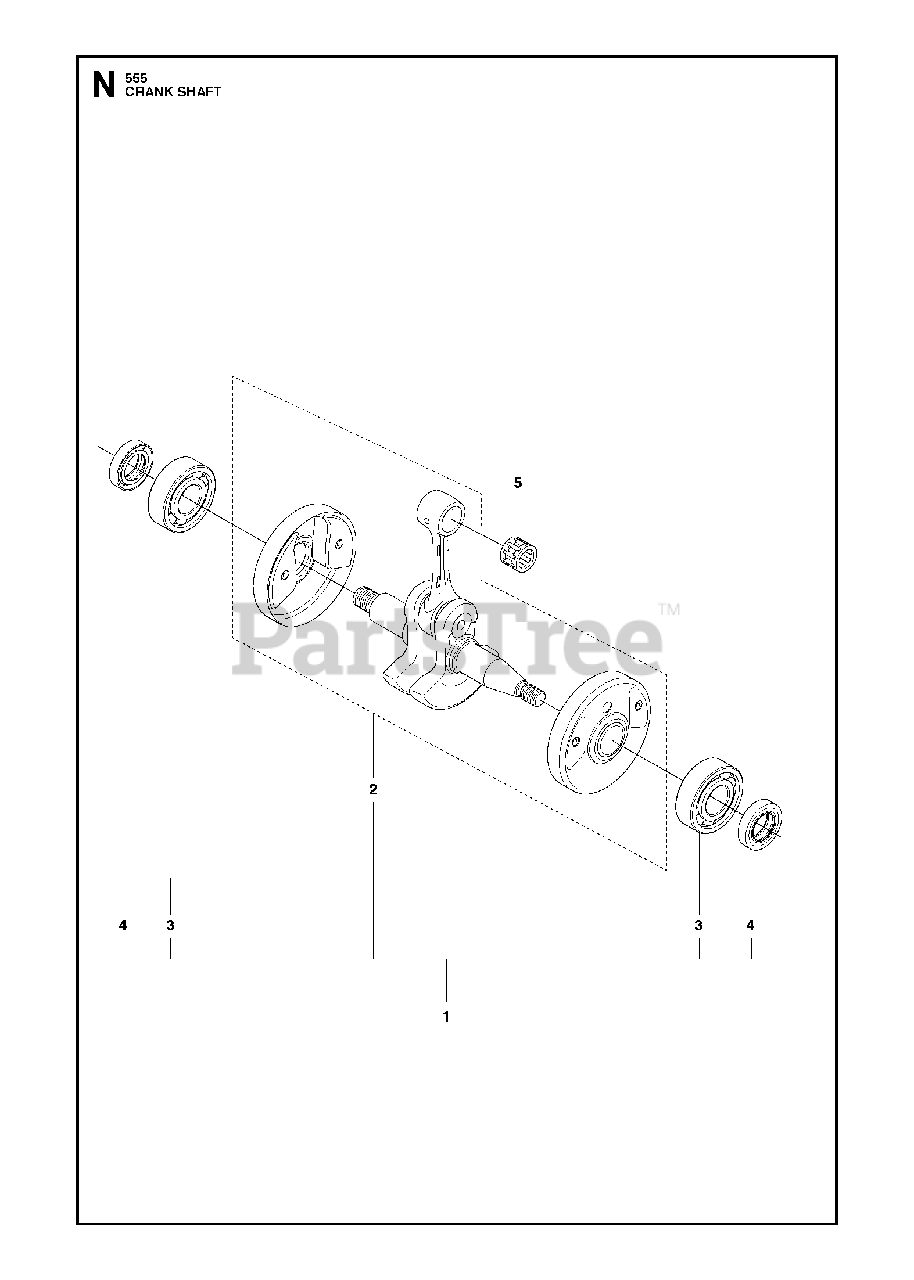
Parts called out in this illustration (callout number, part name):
1	CRANKSHAFT
2	CRANKSHAFT
3	BALL BEARING-6202-C3 SKF
4	SEALING RING
5	SUPPORT BUSHING
